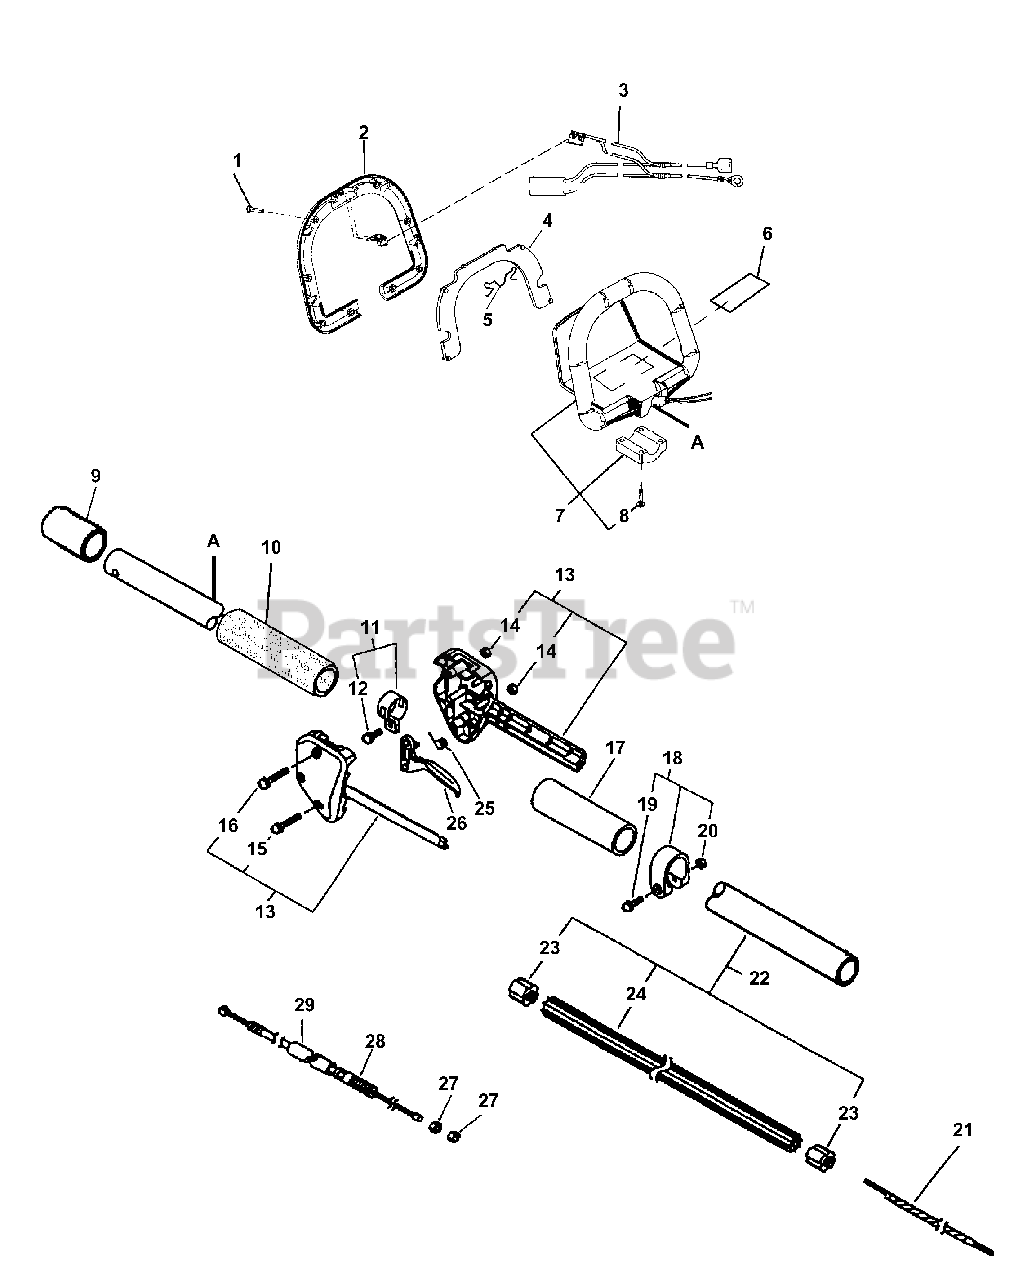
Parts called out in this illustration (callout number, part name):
2	COVER, HANDLE
3	IGNITION SWITCH ASSY
6	LABEL, CAUTION
7	HANDLE ASSY, FRONT
9	COLLAR
10	TUBE
11	CLAMP KIT
12	SCREW 5×14
13	THROTTLE BRACKET SET
14	NUT M5
15	SCREW 5×25
16	SCREW 5×35
17	GRIP, HANDLE
18	CLAMP
19	SCREW 5×28
20	NUT M5
21	DRIVESHAFT - FLEXIBLE
22	MAIN PIPE ASSY
24	LINER - FLEXIBLE
25	SPRING, TORSION
26	TRIGGER, THROTTLE
28	CABLE, THROTTLE
29	TUBE, PROTECTIVE - CORRUGATED
